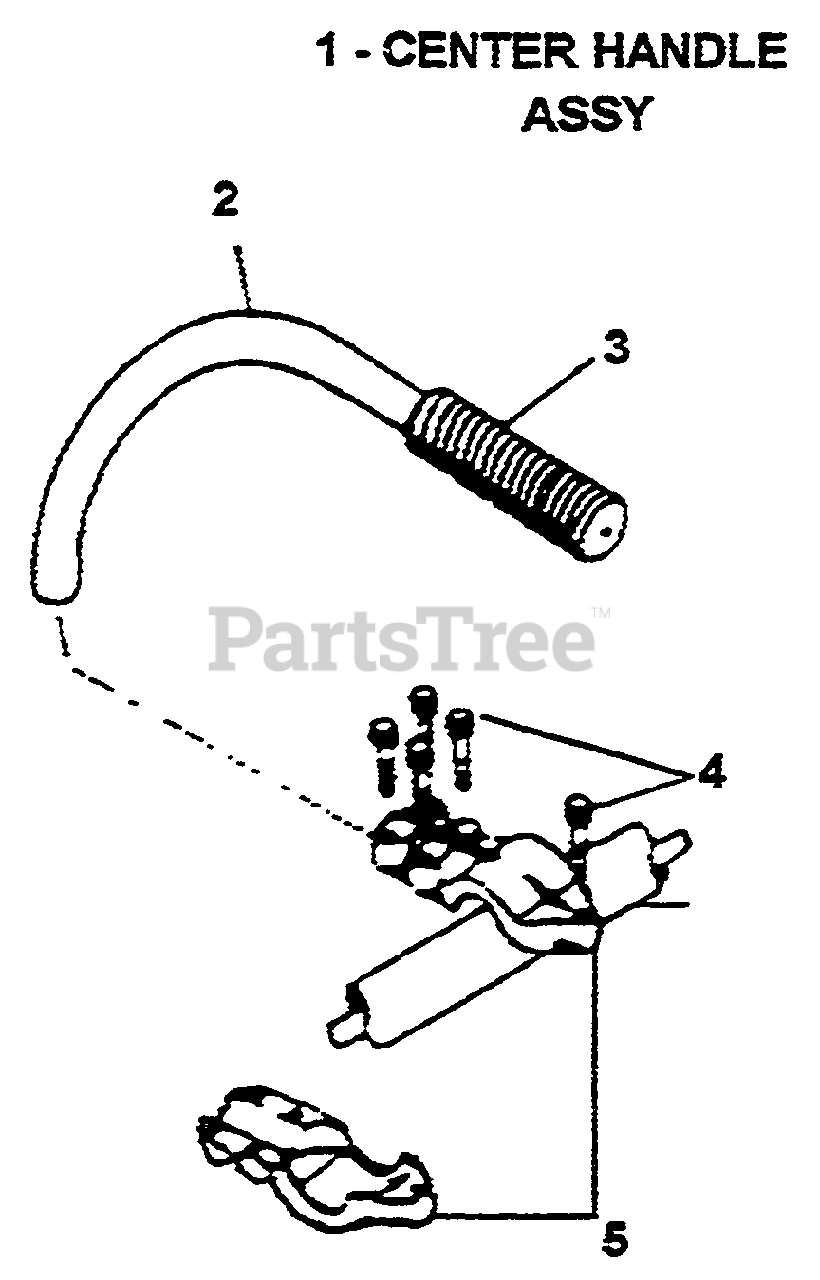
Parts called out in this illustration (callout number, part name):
1	J-HANDLE ASSY
2	HANDLE
3	GRIP
4	SCREWS
5	BRACKET KIT
